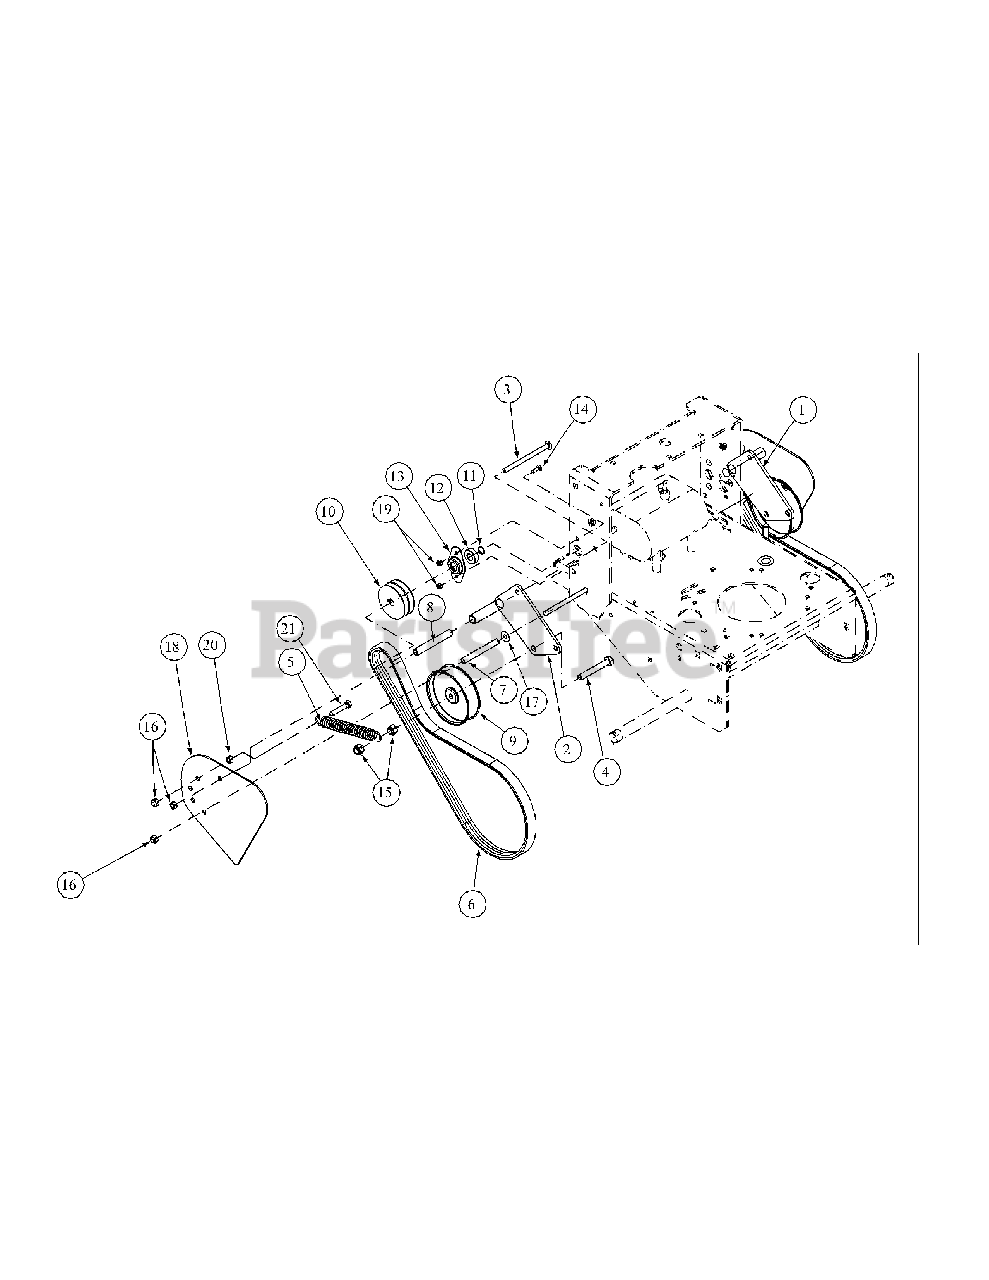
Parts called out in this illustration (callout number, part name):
1	Left Idler Bracket
2	Right Idler Bracket
3	Carriage Bolt, 3/8-16 x 5.50
4	Hex Cap Screw, 1/2-13, 3.50
5	Extension Spring
6	Belt, V
7	Spacer Tube
8	Idler Sleeve
9	Flat Idler Drive
10	Jackshaft Pulley
11	External Retain Ring
12	Bearing
13	Bearing Housing
14	Carriage Bolt, 1/4-20 x .750
15	Lock Nut, Nylon Insert, 1/2-13
16	Lock Nut, Nylon Insert, 3/8-16
17	Flat Washer, 3/8 Zinc
18	Belt Guard
19	Lock Nut, Nylon Insert, 1/4-20
20	Hex Nut, 3/8-16
21	Hex Cap Screw, 3/8-16, 2.00
